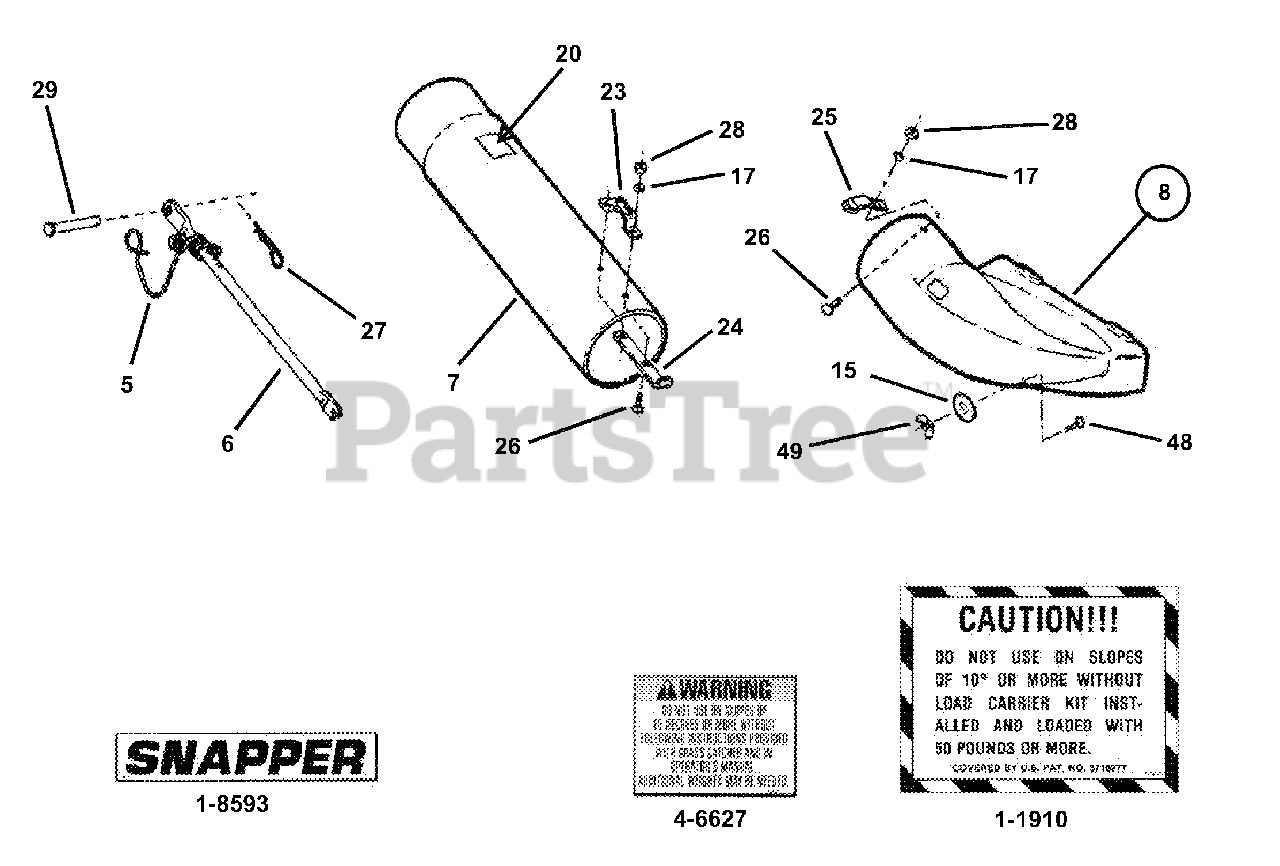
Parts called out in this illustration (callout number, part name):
1-1910	DECAL, GRASS CATCHER
1-8593	DECAL, SNAPPER
4-6627	DECAL, GRASS BAG WARNING
5	ASSEMBLY, Spring & Hook
6	BRACE, Rear (24-1/2" Long)
7	TUBE, Grass (46" long)
8	ADAPTER,
15	WASHER, 5/16" Flat
17	WASHER, 1/4" Internal Tooth Lock
20	DECAL, Caution
23	HANDLE, Tube
24	BASE, Tube Handle
25	LATCH, Chute Tube
26	SCREW, 1/4-20 x 3/4" Mach.
27	PIN, 3/32 x 1-1/2" Hair
28	NUT, 1/4-20 Hex Flange Lock
29	PIN, 5/16 x 1-11/16" Clevis
48	BOLT, 5/16-18 x 1" Carriage
49	WING LOCKNUT, 5/16-18
